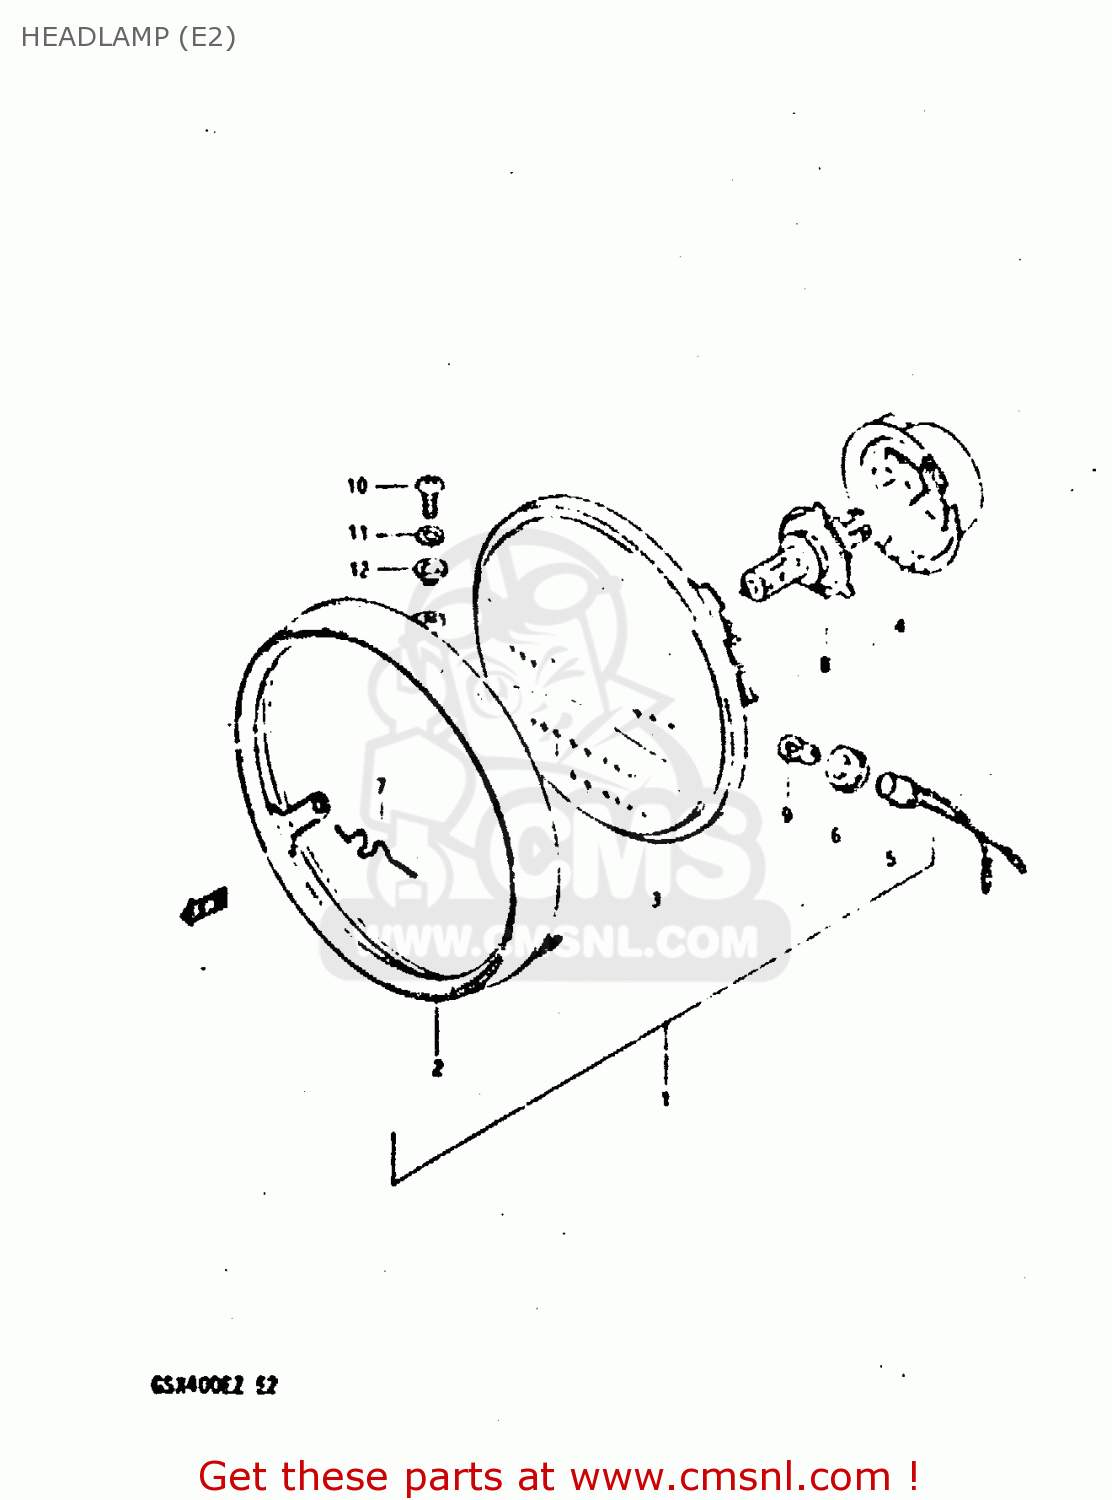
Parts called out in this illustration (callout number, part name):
1	HEADLAMP ASSY
2	RIM
3	LAMP UNIT
4	COVER,SOCKET
5	SOCKET
6	JOINT,RUBBER
7	SPRING
8	BULB(12V60/55W,H4)
9	BULB(12V3.4W,STANLEY,A72A)
10	SCREW
11	WASHER,LOCK
12	WASHER
